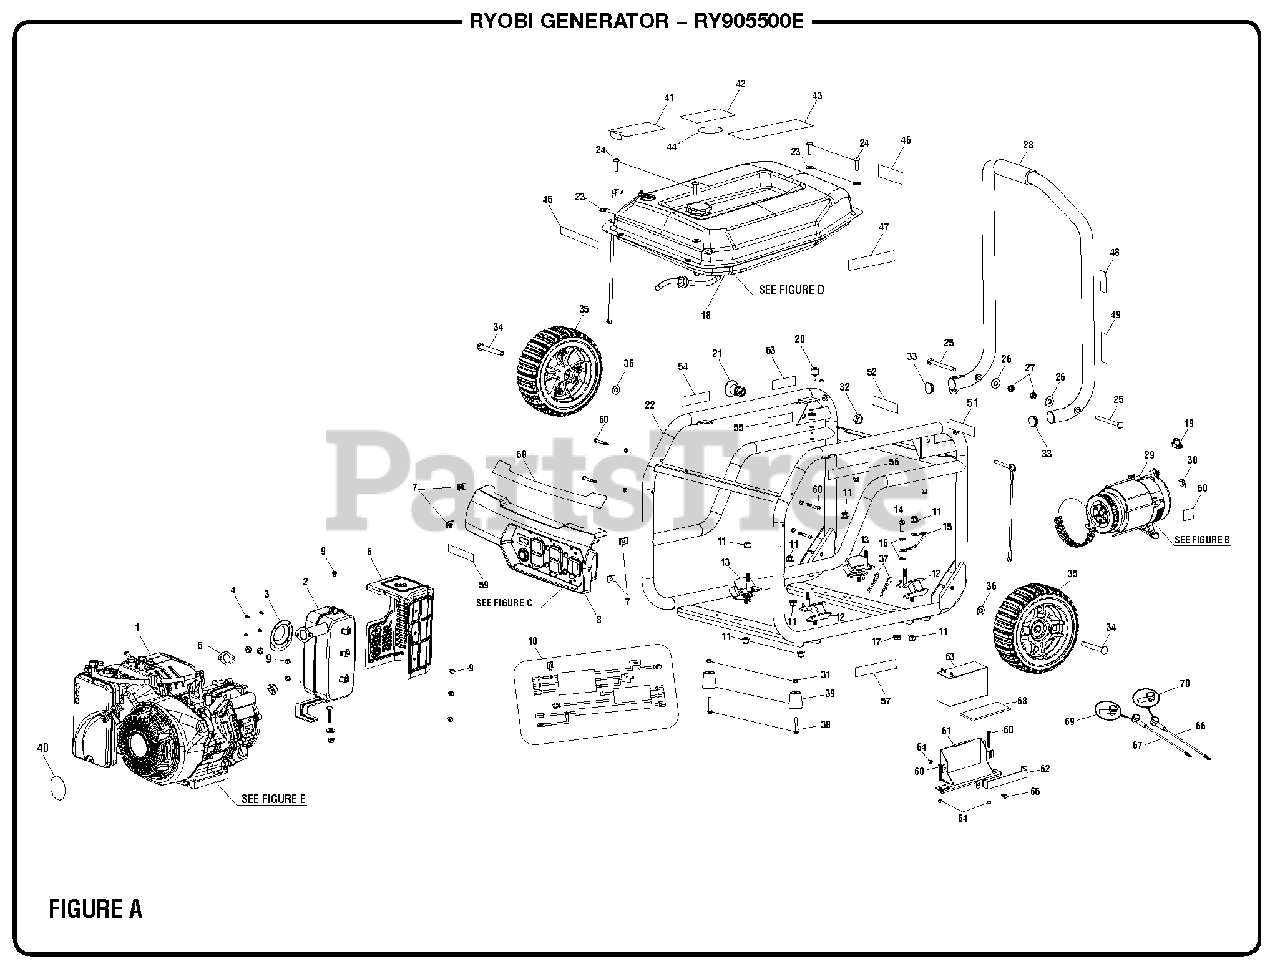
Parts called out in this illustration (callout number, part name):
3	Spark Arrester
4	Screw (8-32 x 3/8 in.)
5	Exhaust Gasket
6	Heat Shield
7	U-Clip (M6)
8	Control Panel Assembly
9	Bolt (M6 x 9 mm, Hex Flange Hd.)
10	Wire Assembly
11	Lock Nut (M8)
12	Isolator (Large)
13	Isolator (Small)
14	Bolt (5/16-18 X 0.75 in.)
15	Ground Wire Assembly
16	Star Washer (5/16 in.)
17	Flange Nut (5/16-18)
18	Fuel System
19	Rubber Boot
20	Handle Bumper
21	Quick Release Pin
22	Carrier Assembly
23	Washer (1/4 in., Type A)
24	Screw (1/4-20 x 1 in., T30 Torx Hd.)
25	Handle Pivot Bolt.
26	Washer (5/16 in.)
27	Lock Nut (5/16-18)
28	Handle Assembly
29	Generator Head Assembly
30	Ground Lug
31	Lock Nut (M8)
32	Lock Nut (1/2-20)
34	Axle Bolt
36	Washer (M10)
37	Hitch Pin
38	Bolt (M8 x 45 mm, Hex Flange Hd.)
40	Recoil Label
41	Notice Hangtag
42	Warning Label
43	CPSC Label
44	Fuel Stabilizer Label
45	Logo Label
46	Combustion Warning Label
47	Start Label
48	Fuel Stabilizer Label (SP/FR)
49	E85 Label
50	Ground Label
51	Ground Warning Label
52	Fire Danger Label
53	Pin Release Label
54	Inquiries Label
56	Fire Distance Label
57	Lubricant Label
58	Performance Label
59	Choke Label
60	Screw (M6 x 50 mm, T30 Torx Hd. )
61	Battery Tray
62	Battery Bracket
63	Battery Bracket
64	Lock Nut (M6)
65	Bolt (M6 x 16 mm, Hex Hd.)
66	Battery Cable (Red)
67	Battery Cable (Black)
68	Battery Tray Gasket
69	Rubber Battery Cable Boot (Black)
70	Rubber Battery Cable Boot (Red)
